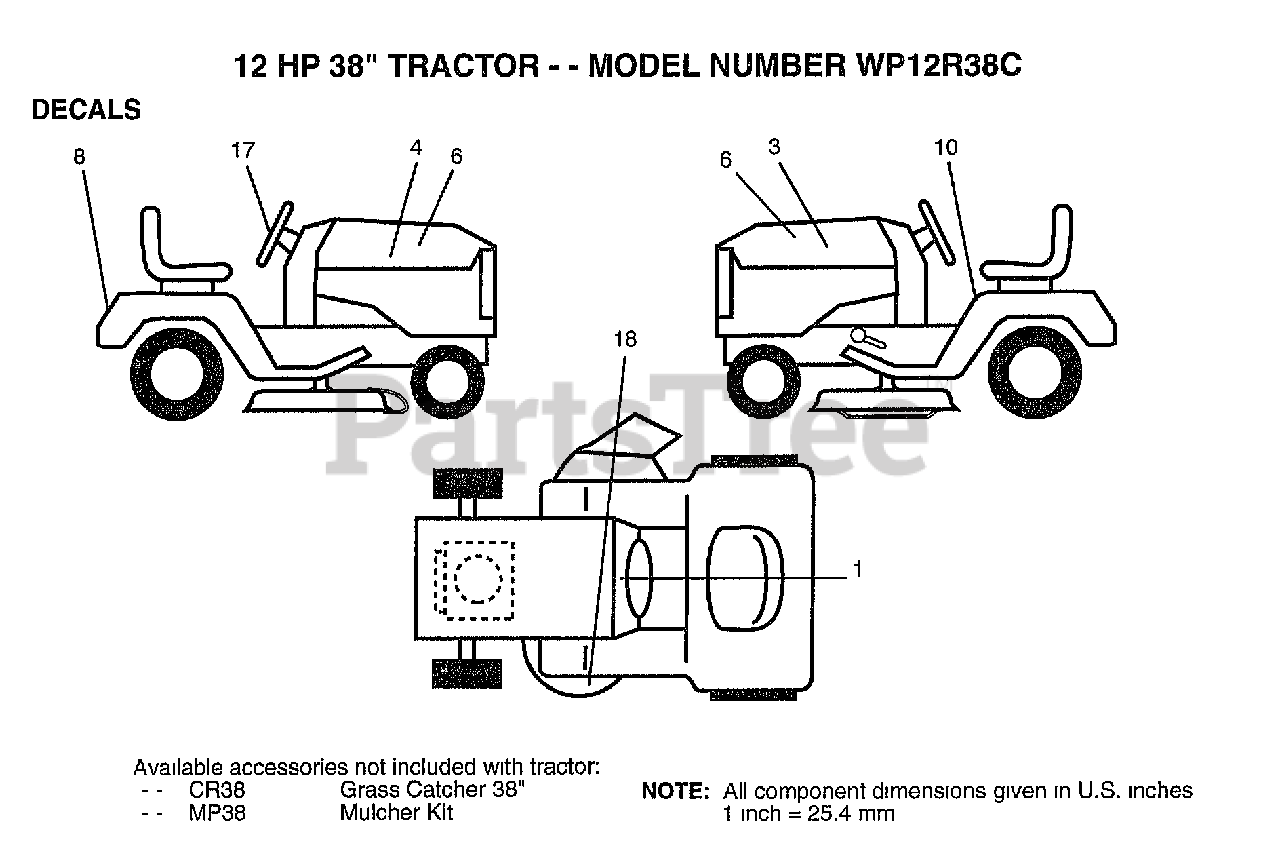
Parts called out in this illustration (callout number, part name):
1	DECAL.INST.OPER
6	DECAL.HOOD.LOGO.
8	DECAL, FENDER LOGO
10	DECAL
17	DECAL, WHEEL CAP
